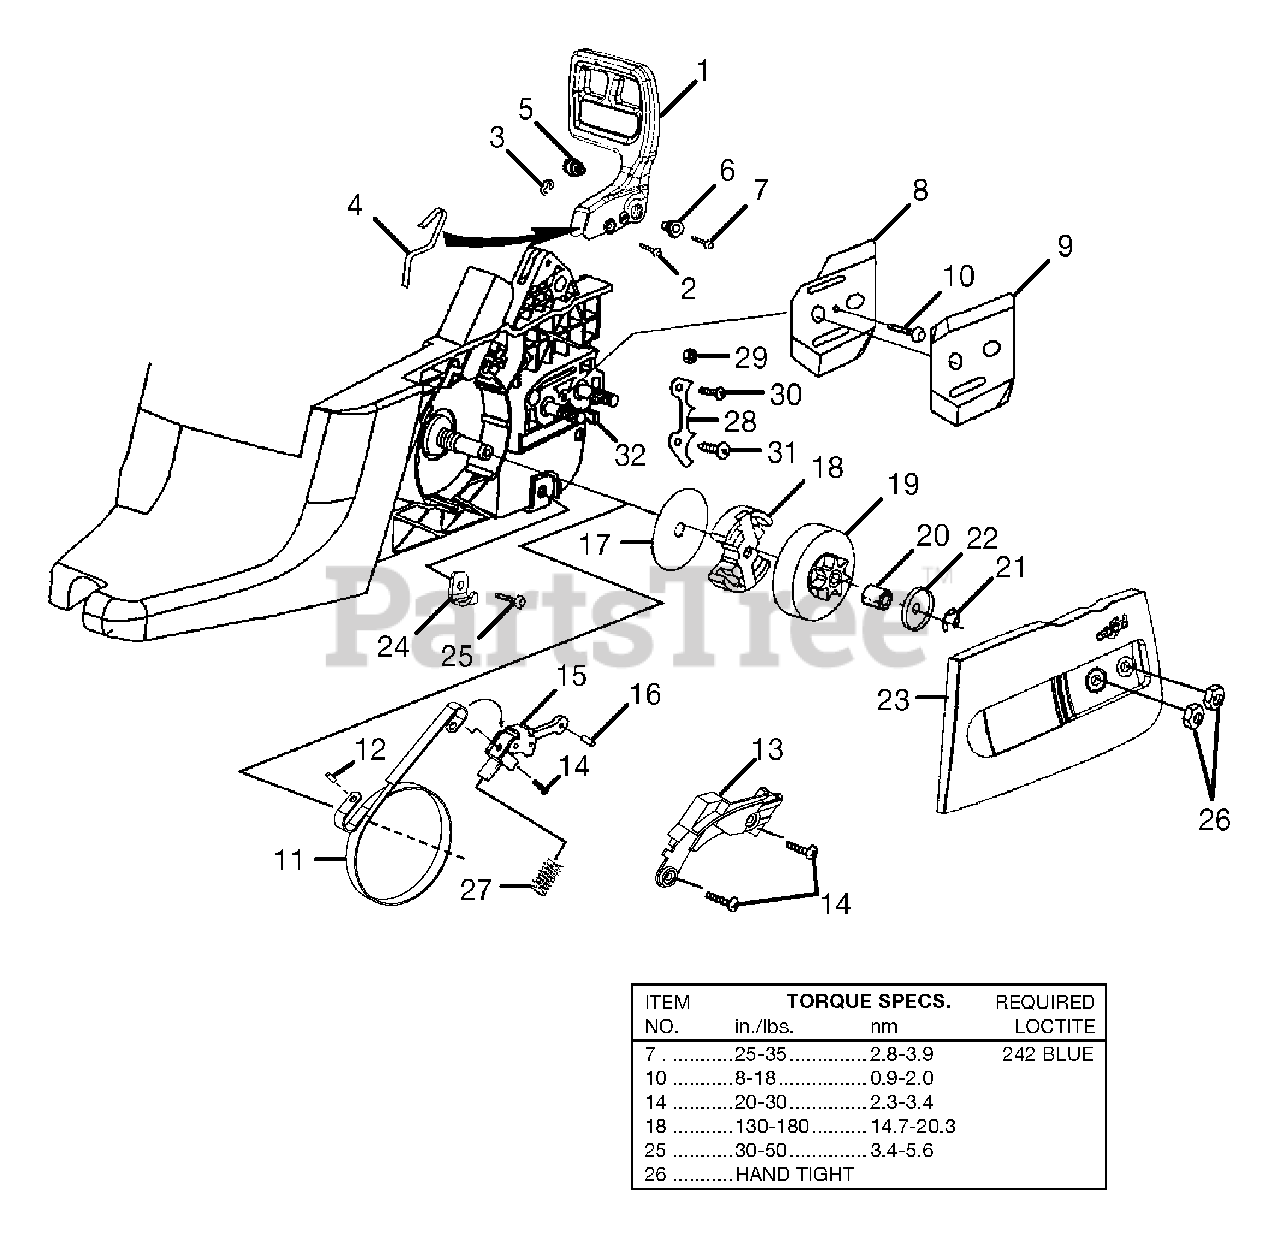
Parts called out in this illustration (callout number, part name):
1	HAND GUARD
2	HAND GUARD ACTUATING PIN
3	RETAINING RING
4	SPRING, HANDGUARD
5	PIVOT, LH
6	PIVOT, RH
7	SCREW (8-32 x 5/8 in.)
8	PLATE, GUIDE BAR
9	PLATE, GUIDE BAR
10	SCREW (6-19 x 1/2 in.)
11	BRAKE BAND
12	PIN, ROLL
13	BRAKE BAND COVER
14	SCREW (8-16 x .320 )
15	CHAIN BRAKE LINK
16	PIN, ROLL
17	THRUST WASHER
18	CLUTCH & HARDWARE
19	SPROKET DRUM (.325 PITCH)
20	BEARING, NEEDLE
21	RING, RETAINING
22	WASHER
23	DRIVE CASE COVER
24	CHAIN CATCHER
25	SCREW (10-24 x 1/2 in.)
26	NUT, HEX
27	SPRING, COMPRESSION
28	BUMPER SPIKE
29	LOCK NUT, HEX (10-24)
31	SCREW, TRUSS HD.
32	ADJUSTING PIN KIT
